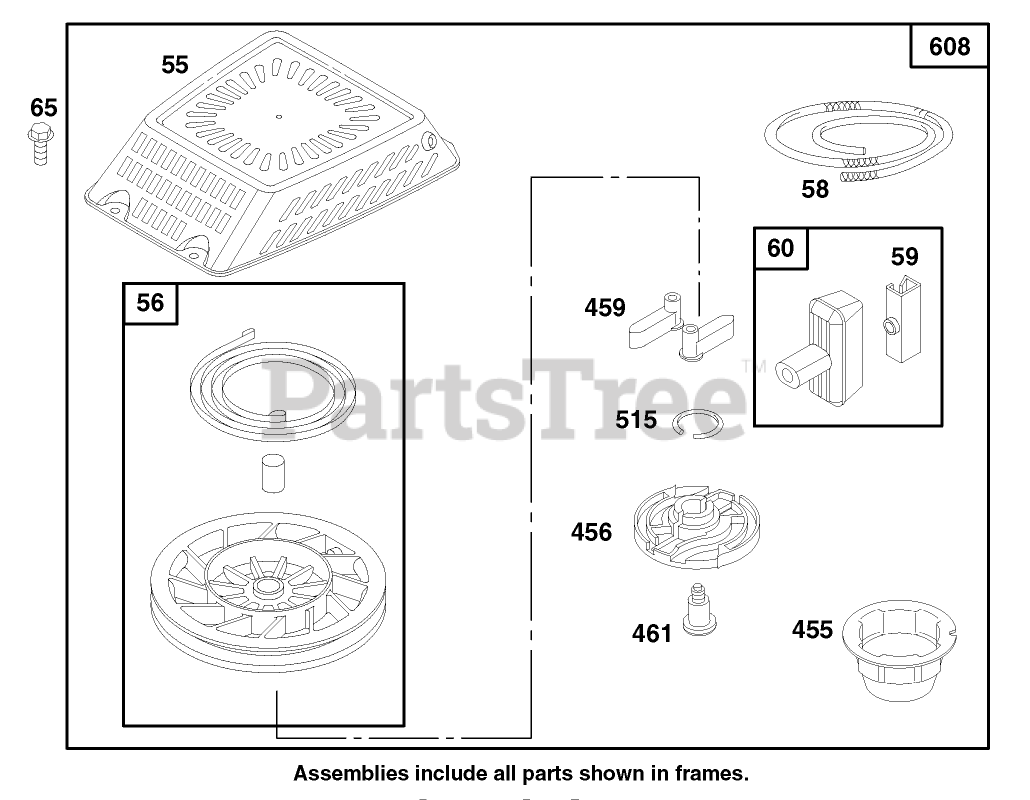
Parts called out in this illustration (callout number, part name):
56	PULLEY-STARTER, REWIND
58	ROPE-STARTER
59	INSERT-HANDLE, REWIND
455	CUP - STARTER
456	RETAINER-STARTER, REWIND
459	PAWL-STARTER
515	SPRING-TORSION
608	BRIGGS #498146
